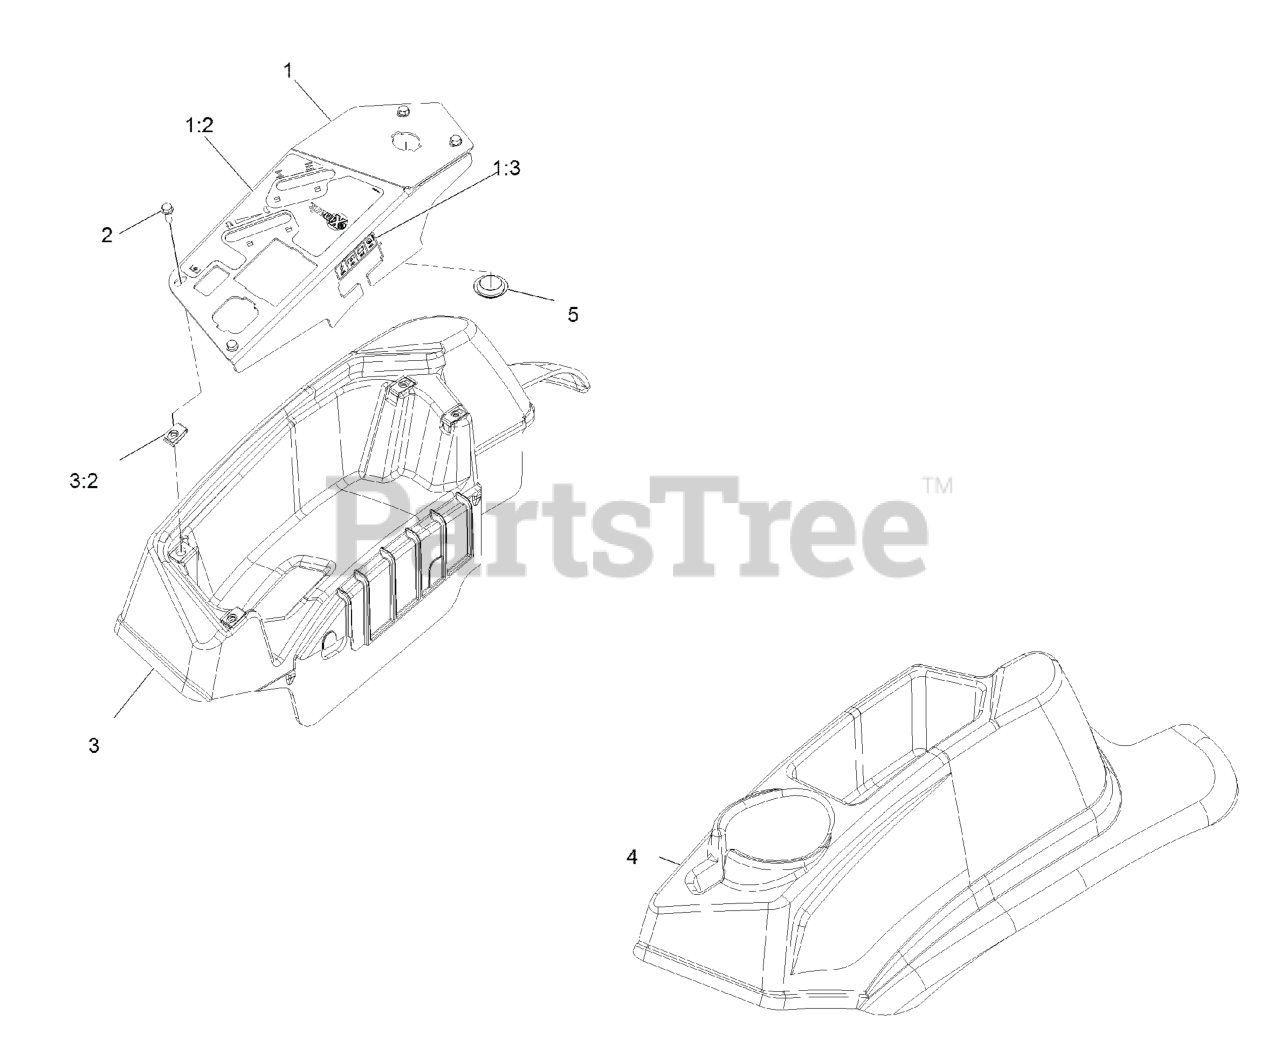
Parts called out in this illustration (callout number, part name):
1	ASM-PANEL, CONTROL W/DECAL
1:2	DECAL-CONTROL PANEL NON-EFI
1:3	DECAL-FUSES
2	SCREW-HWH
3	CONSOLE,RH AS ASM
4	CONSOLE, LH AS
5	PLUG-PLASTIC
